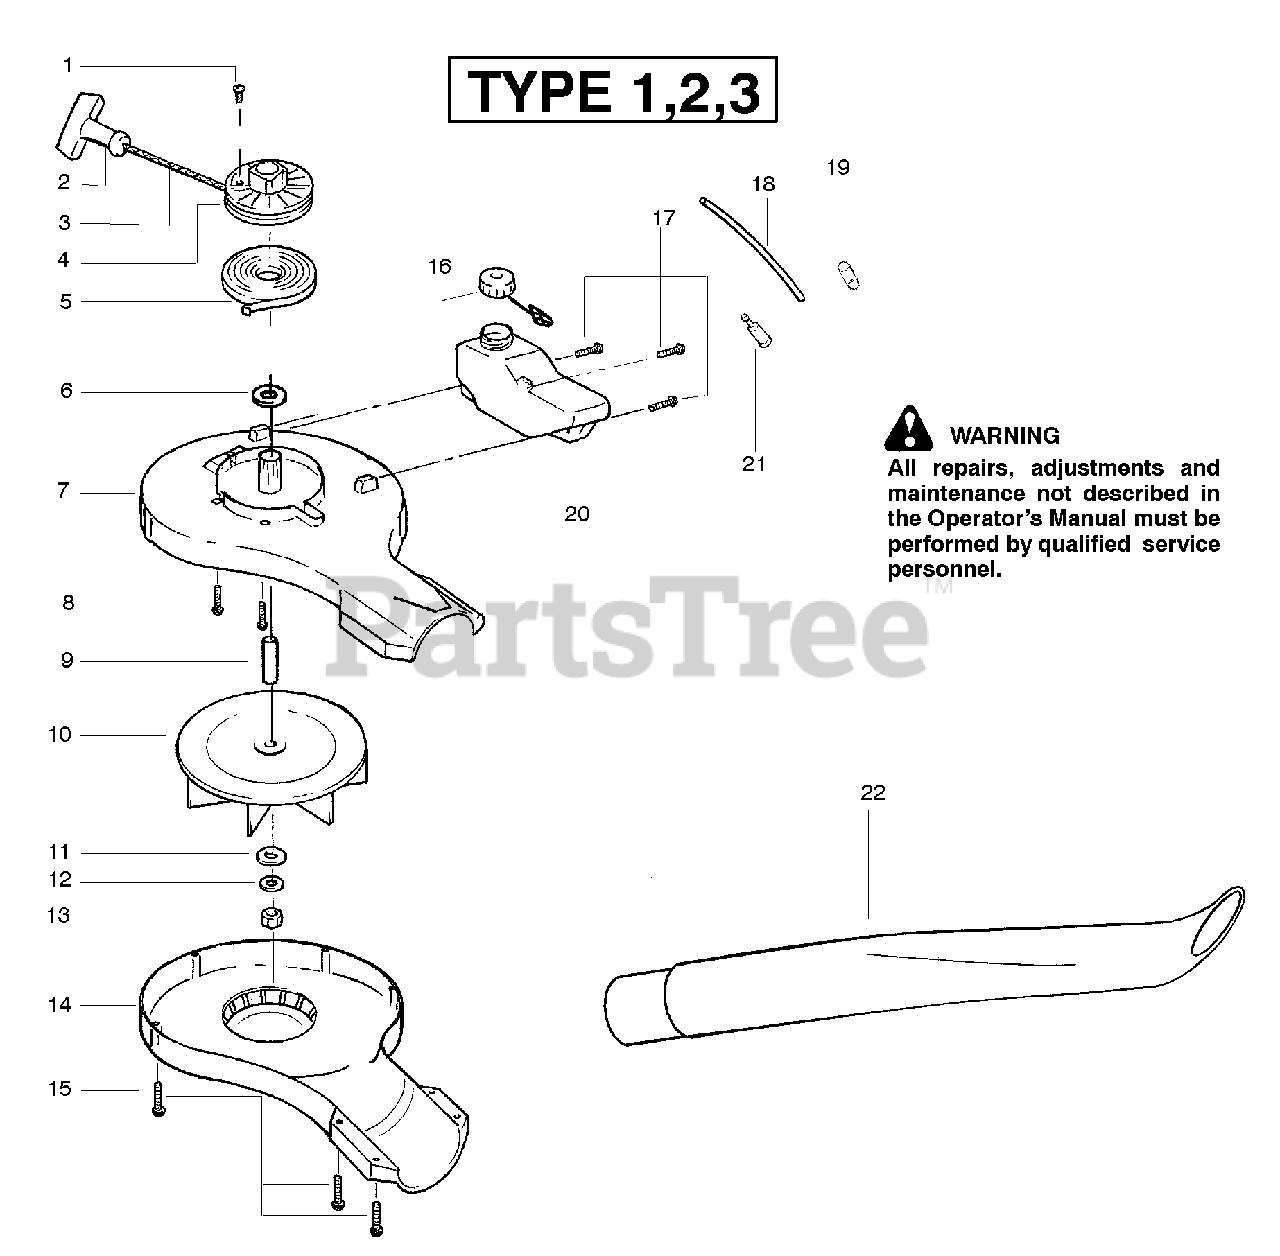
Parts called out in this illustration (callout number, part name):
2	Handle-Starter
3	Kit-Rope
4	Kit-Starter Pulley
5	Spring-Starter
7	Housing-Impeller (Upper)
9	Spacer-Flywheel
10	Assy-Impeller
11	Washer-Flat
12	Lockwasher
14	Assy-Impeller Housing (Lower)
16	Assy-Fuel Cap
18	Kit-Fuel Line
19	Grommet-Fuel Line
20	Assy-Fuel Tank
21	Fuel Pick-up Ass'y.
22	Tube-Blower
